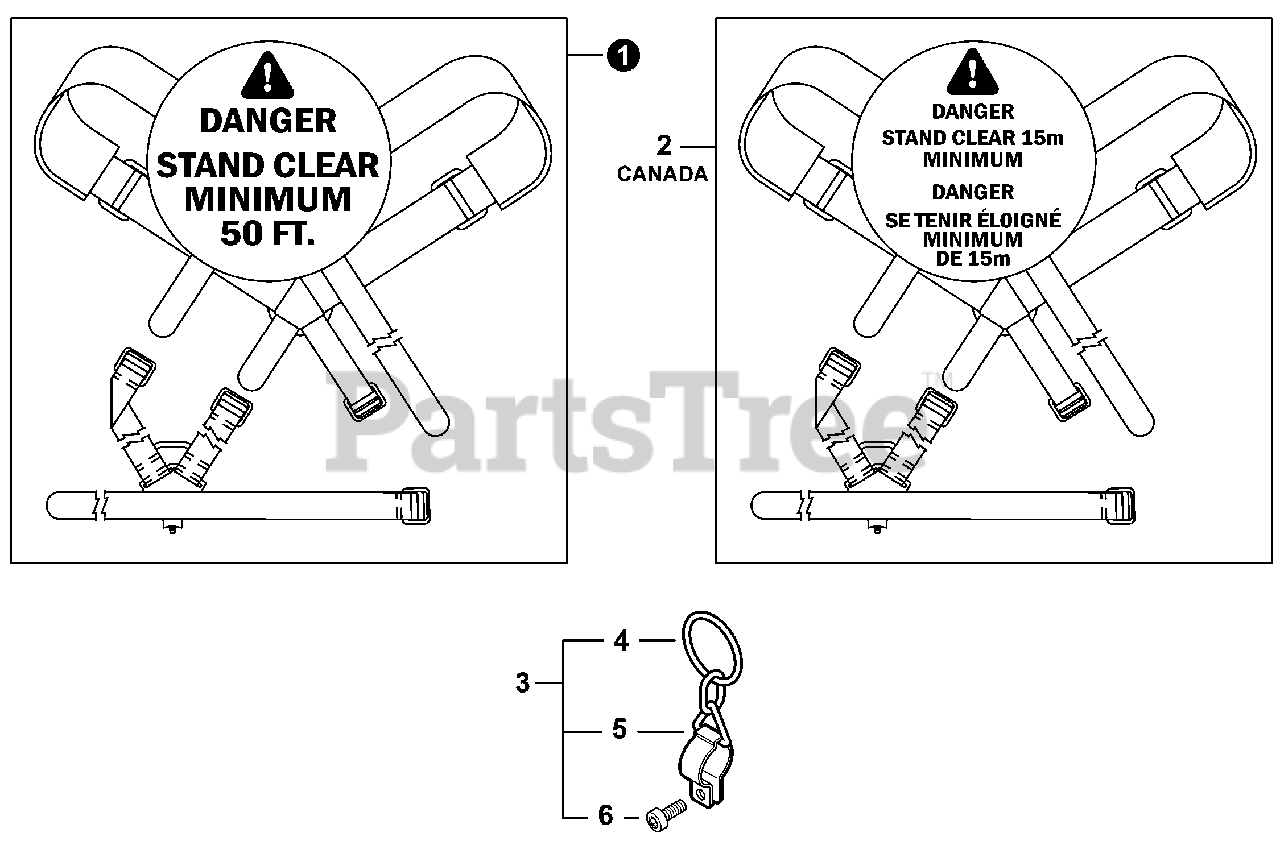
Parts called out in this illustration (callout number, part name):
1	HARNESS, SHOULDER
2	HARNESS, SHOULDER
3	HANGER ASSY, HARNESS
4	RING, HARNESS
5	HANGER, HARNESS
6	BOLT 5×12
